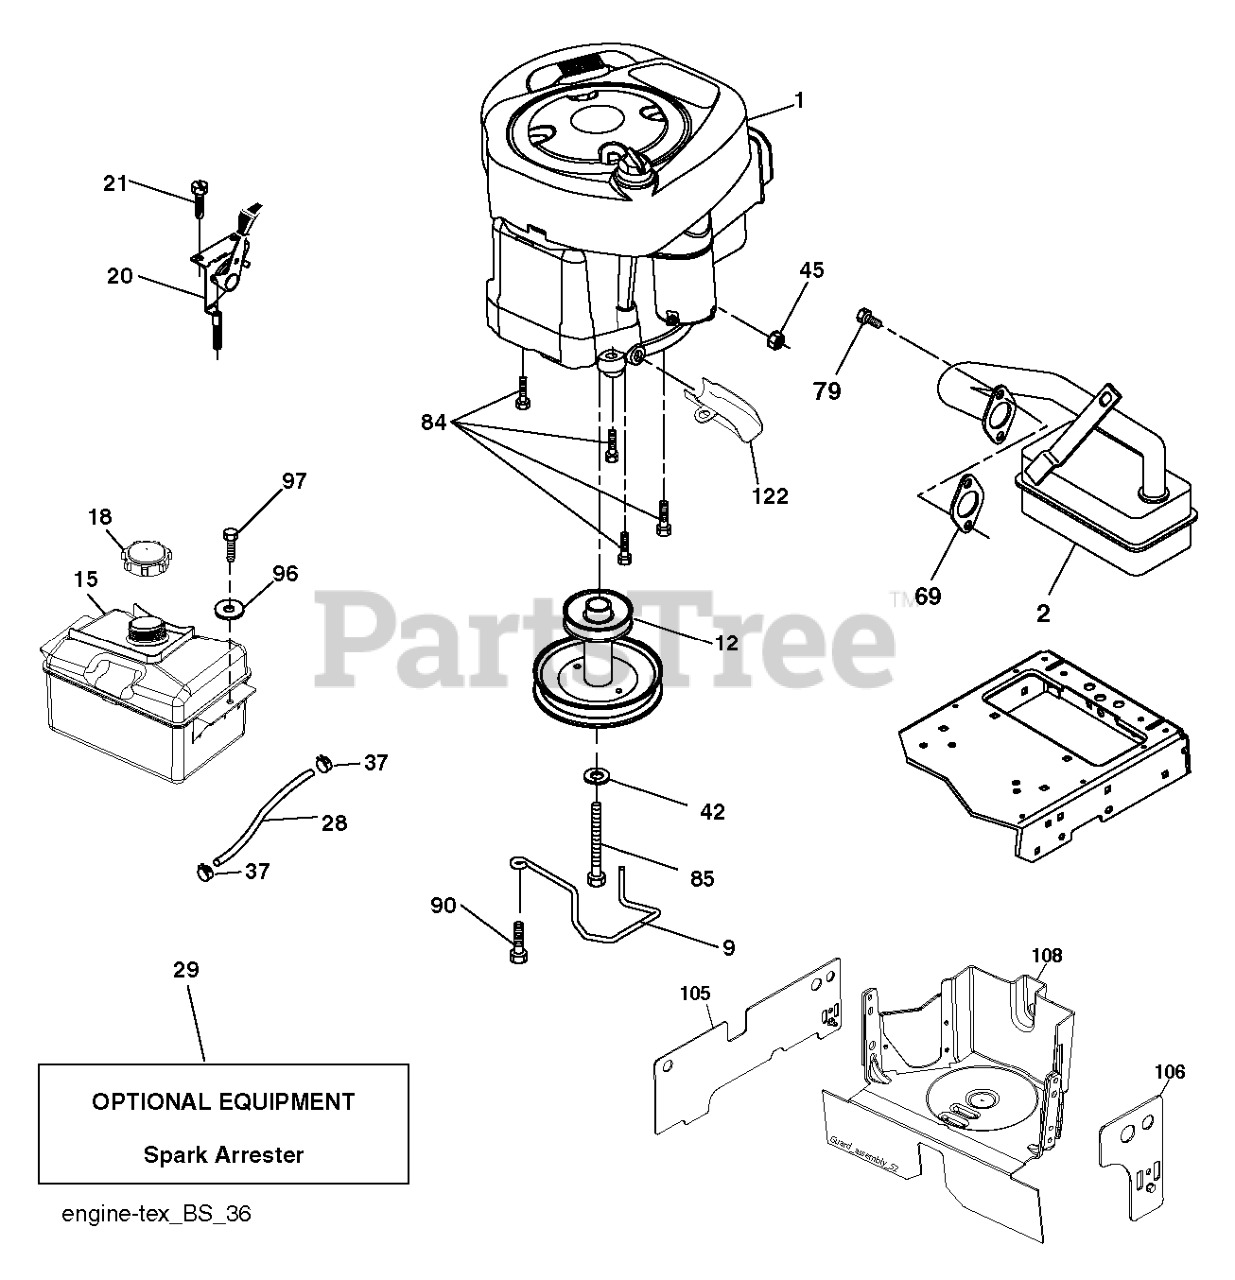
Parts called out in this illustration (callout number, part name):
2	MUFFLER.B&S.MODEL.21.11HP.OHV
9	KEEPER.BELT.ENGINE.3.25 (3 2)
12	PULLEY.ENG.CL.MECH.SLVR.LT/YT
15	RP TANK FUEL FRT 1.5 GAL
18	CAP ASM.FUEL.2.25"FR.
20	CONTROL.TH/CK.C.
21	SCREW.#10 X 0.750.BOS
28	LINE.FUEL.20
29	KIT.SPARK ARRESTOR 794945 B&S
37	HOSE CLAMP
42	LOCKWASHER
45	NUT
69	REPL BY 532 27 22-93
79	SCREW.SOCKET HD.5/16-1
84	SCREW.3/8-16
85	BOLT HEX 7/16-20X4-1/4"
90	SCREW 3/8-16X1
97	SCREW HEXWSHR 1/4-20X3/4
105	SHIELD LEFT
106	SHIELD SIDE
108	COVER PULLEY
122	EXTENSION DRAIN OIL
